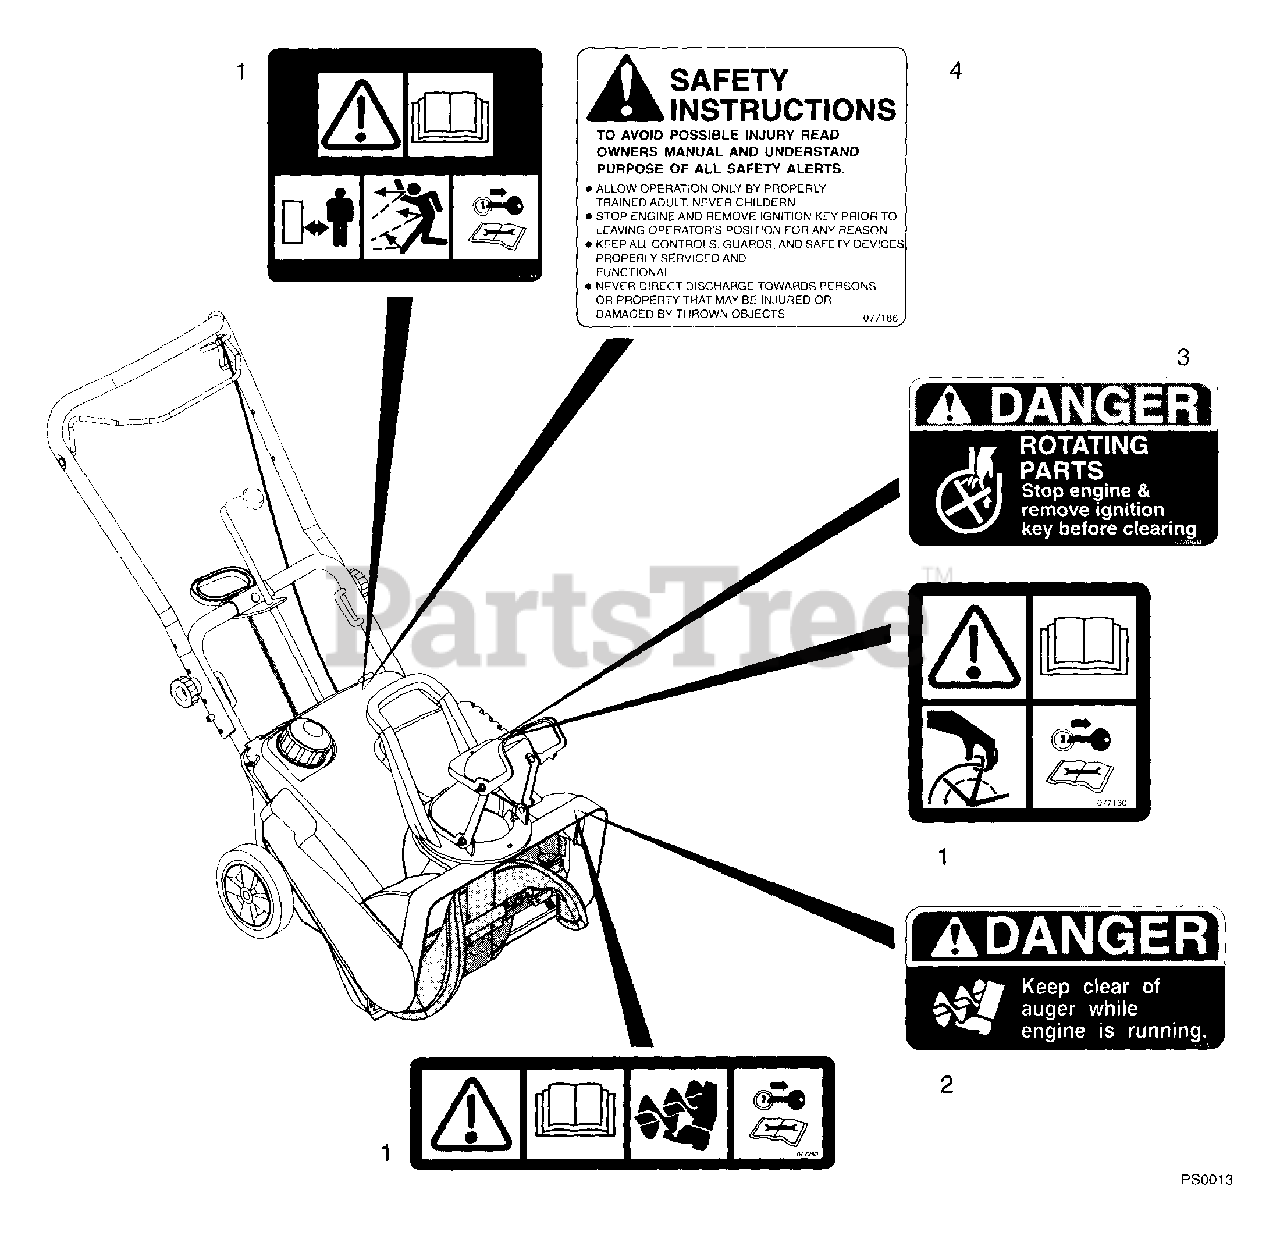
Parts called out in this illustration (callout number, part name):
1	DECAL SET-38000 SERIES-CE
2	DECAL - DANGER
3	DECAL-DANGER ROTATING PARTS
4	DECAL-SAFETY INSTRUCTION
